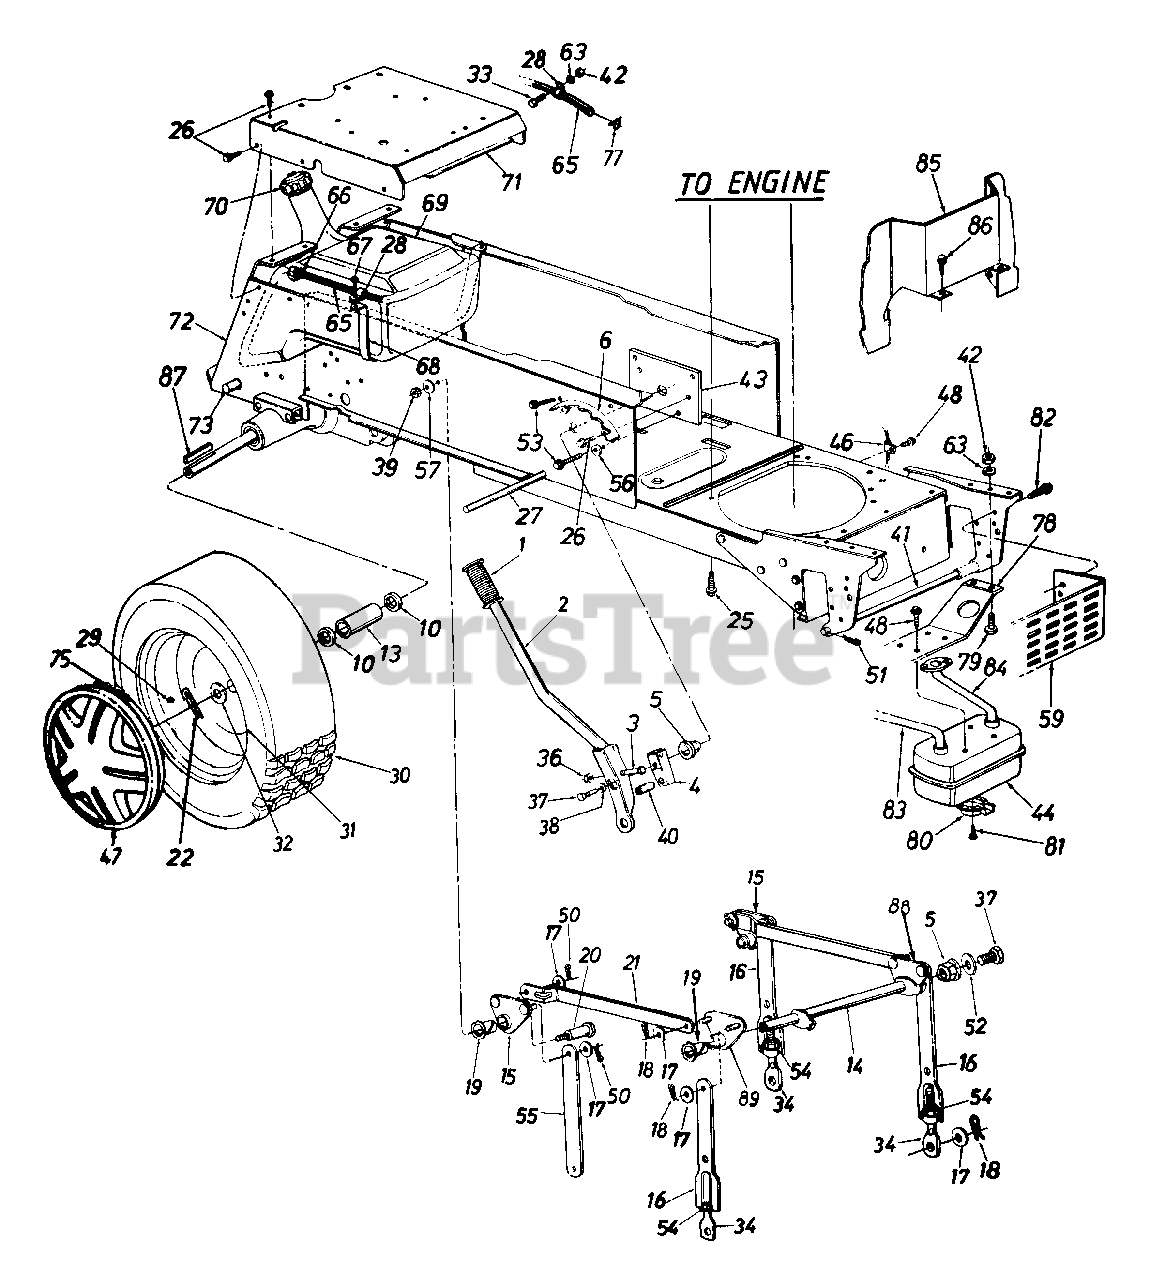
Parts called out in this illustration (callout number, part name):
1	Grip
2	Lift Handle Ass'y.
3	Hex Bolt 5/16-18 x 1.5" Lg.
4	Lift Shaft Drive
5	Plastic Hex Brg. 5/8" I.D.
10	Fl-Wash. 1.03" I.D. x 1.62" O.D.
13	Spacer 1" I.D. x 1.25" O.D.
14	Lift Shaft Ass'y.
15	Lift Pivot Brkt. Ass'y.
17	Fl-Wash. 1/2" I.D. x 1.00" O.D. x .090"
18	Hairpin Cotter
19	Flanged Brg. 5/8" I.D.
20	Shld. Bolt 5/8" Dia. x .96" Lg. 3/8-16
25	Hex Wash. Hd. Scr. 3/8-16 x 1.25" Lg.
26	Hex Thd. Rolling Ser. 5/16-18 x .75" Lg.
27	Running Board Rod
29	Air Valve
33	Hex Bolt 1/4-20 x .62" Lg.
34	Eye Bolt Adj. Link 1/2-13 Thd.
36	Hex Cent. L-Nut 5/16-18 Thd.
37	Hex Bolt 5/16-24 x .75" Lg. (Gr. 5)
39	Hex Top L-Nut 3/8-16 Thd.
40	Compression Spring
41	Deck Connecting Rod
42	Hex Nut 1/4-20 Thd.
46	Mounting Clamp
47	Hub Cap
48	Hex Wash. Hd. TT-Tap Scr. 1/4-20 x .5" Lg.
50	Cotter Pin .09 Dia. x 1.0" Lg.
51	Int. Cotter Pin
52	Flat Wash. .34" I.D. x 1.12" O.D. x .125"
53	Hex Wash. Hd. AB-Tap Scr. 5/16-18 x .5" Lg.
54	Hex Nut 1/2-13 Thd.
56	Fl-Wash. .344" I.D.
57	Bell-Wash. .4" I.D. x 1.13" O.D.
59	Heat Shield
63	L-Wash. 1/4" I.D.
65	Fuel Line 46" Lg.
67	Hex AB-Tap Scr. 1/4 x .62" Lg.
68	Fuel Tank Strap
75	Spring Clip
78	Muffler Mounting Brkt.
79	Hex Bolt 1/4-20 x .62" Lg.
80	Muffler Deflector
81	Hex Wash. Hd. F-Tap Scr. #8 x .32" Lg.
82	Hex Wash. Hd. TT-Tap Scr. 5/16"-18 x .62" Lg.
83	Exhaust Tube - R.H.
84	Exhaust Tube - L.H.
87	Sq. Key 1/4" x 3" Lg.
88	Lift Pivot Brkt. - L.H.
89	Lift Pivot Brkt. - R.H.
